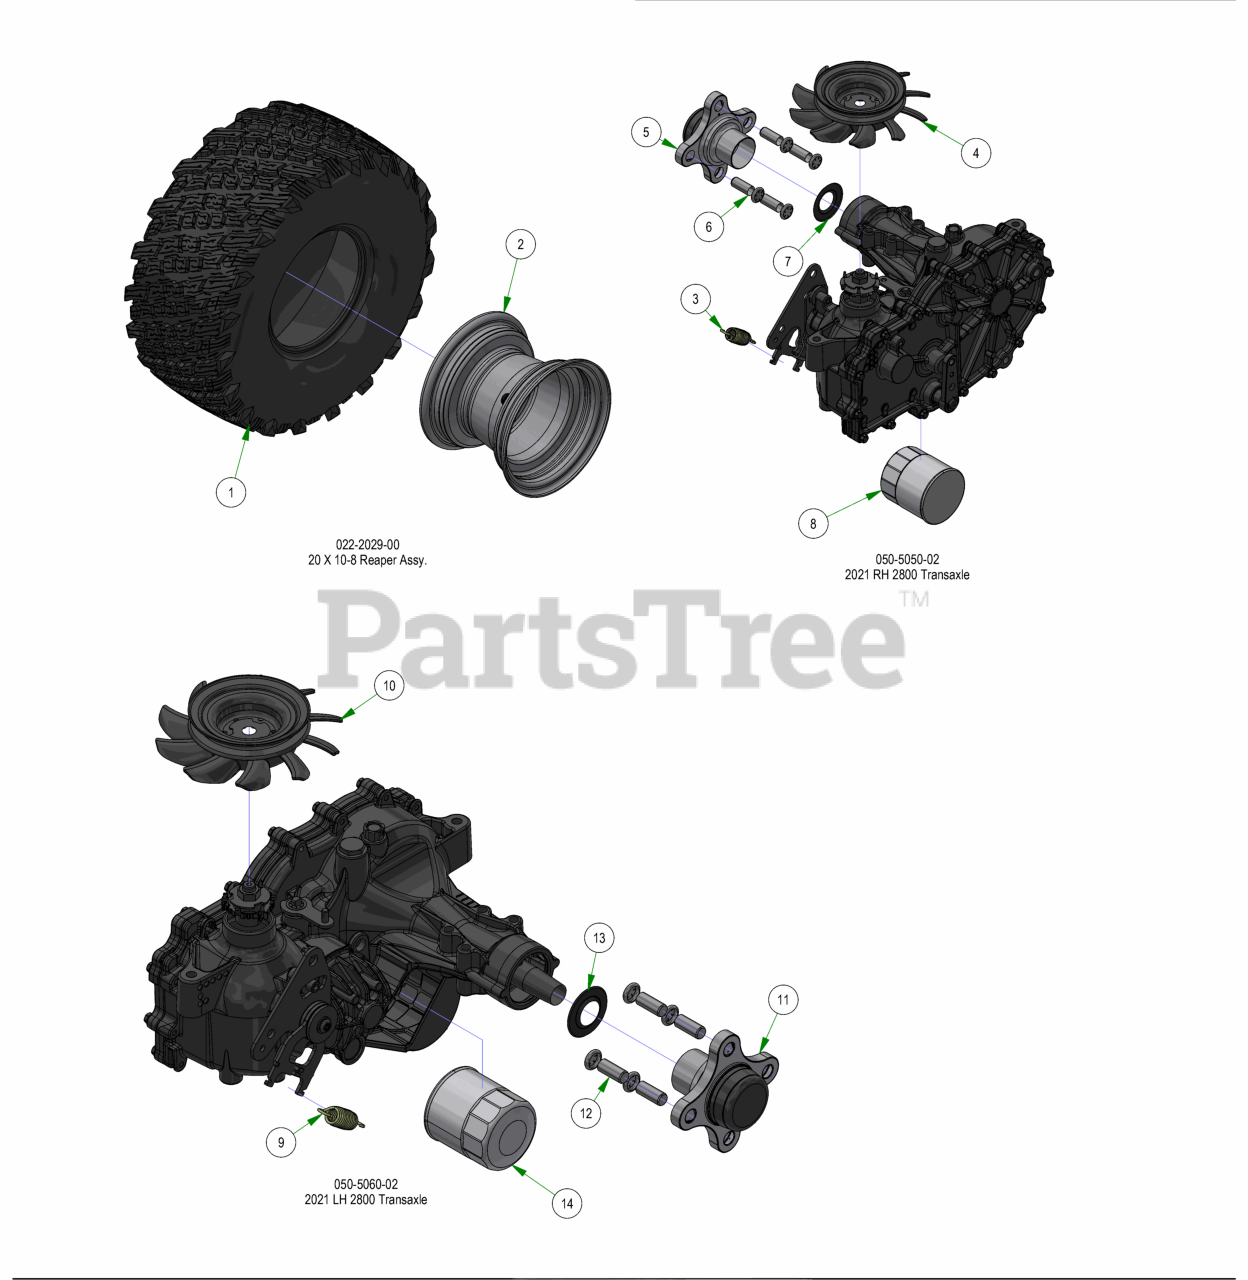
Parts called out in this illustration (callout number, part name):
1	20x10-8 4P A2103 Tire Only
2	8 x 6.375 4H Black Wheel Only
3	Transaxle Spring
4	2021 ZT/Maverick Transaxle Fan/Pulley Kit
5	ZT Transaxle Wheel Hub
6	Transaxle Wheel Studs/ Drum Brake Studs
7	2021 ZT/Maverick Transaxle Seat Kit (ZT-2800)
8	ZT Hydraulic Filter
9	Transaxle Spring
10	2021 ZT/Maverick Transaxle Fan/Pulley Kit
11	ZT Transaxle Wheel Hub
12	Transaxle Wheel Studs/ Drum Brake Studs
13	2021 ZT/Maverick Transaxle Seat Kit (ZT-2800)
14	ZT Hydraulic Filter
